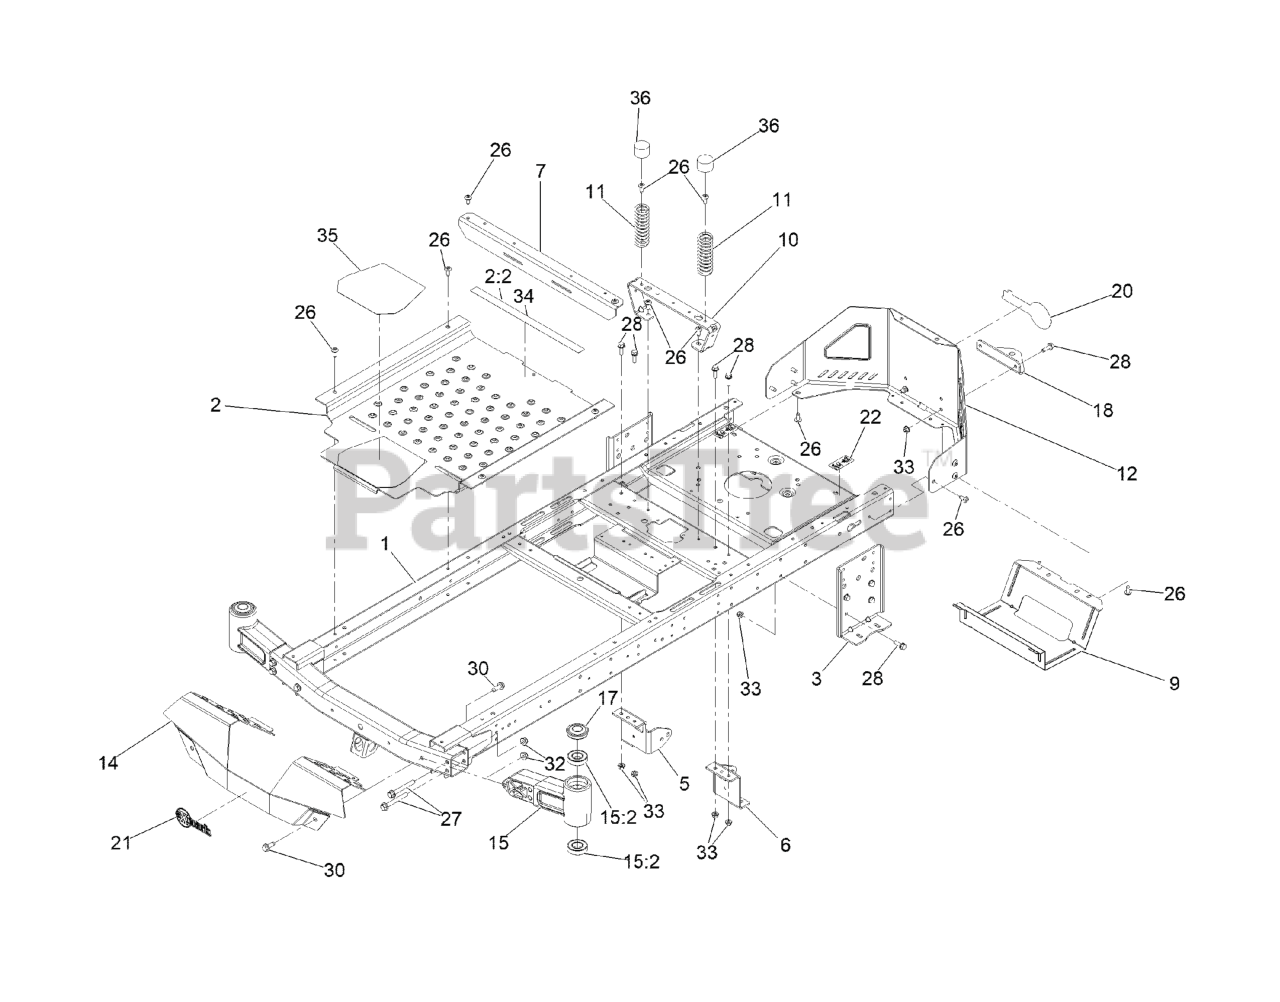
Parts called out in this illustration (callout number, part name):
1	FRAME ASM - RIVETED/WELDED
2	Pan-Floor ASM
2:2	DECAL-WARNING
3	PLATE-MOUNT, HYDRO
5	MOUNT-HYDRO, FRONT (RIGHT
6	Mount-Hydro, Front (Left)
7	BRACE-CROSS
9	GUARD-MUFFLER
10	SUPPORT-SEAT
11	SPRING-COMPRESSION
12	GUARD-ENGINE
15	AXLE-STUB
15:2	BEARING-BALL
17	Cap-Grease
18	BRACKET-HITCH
20	DECAL-EXMARK LOGO
21	DECAL-EXMARK LOGO
22	DECAL-BYPASS
27	SCREW-HHF
28	SCREW-HHF
30	SCREW-HWH
32	NUT-HF, NI
33	NUT-HF, NI
34	DECAL-WARNING
35	TREAD-STEP
36	CAP-PROTECTOR
